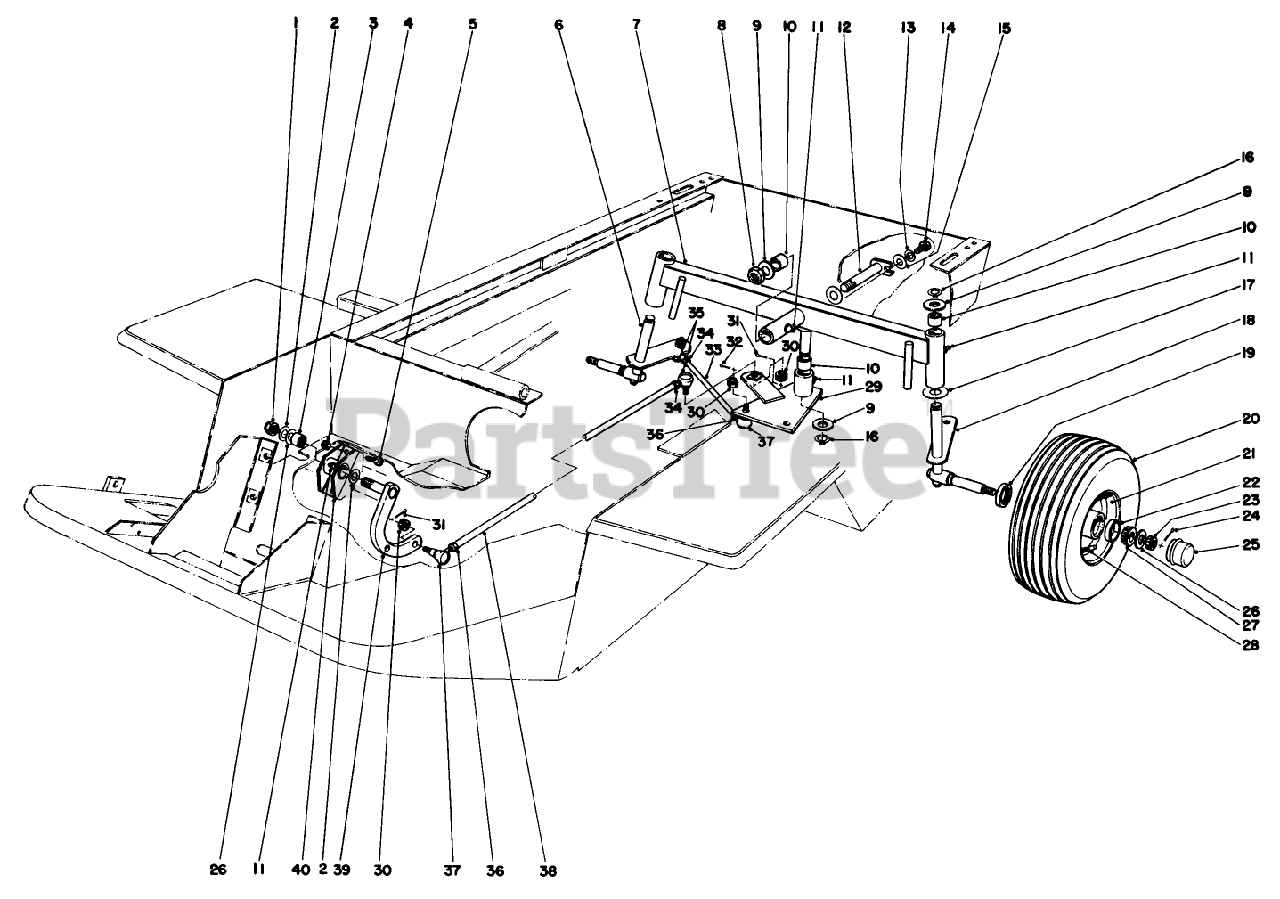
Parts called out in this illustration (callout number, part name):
1	NUT-LOCK, NI
2	THRUST WASHER
3	BEARING-NEEDLE
4	NUT-LOCK, NI
5	SCREW-HH
7	REAR AXLE WA
8	NUT-LOCK, NI
11	FITTING-GREASE
13	SCREW-HH
14	SCREW-HH
15	WASHER-FLAT
16	RING-RETAINING
17	WASHER-THRUST
22	BEARING-CUP, TAPERED
23	NUT-HEX, SLOTTED
24	PIN-COTTER
25	CAP-DUST
26	WASHER-FLAT
27	BEARING-CONE, TAPERED
30	NUT-HEX,SLOTTED
32	SCREW-HH
34	NUT-HEX JAM LH
36	NUT-JAM
38	REAR STRG TUBE *PP
39	PIVOT ARM WA
